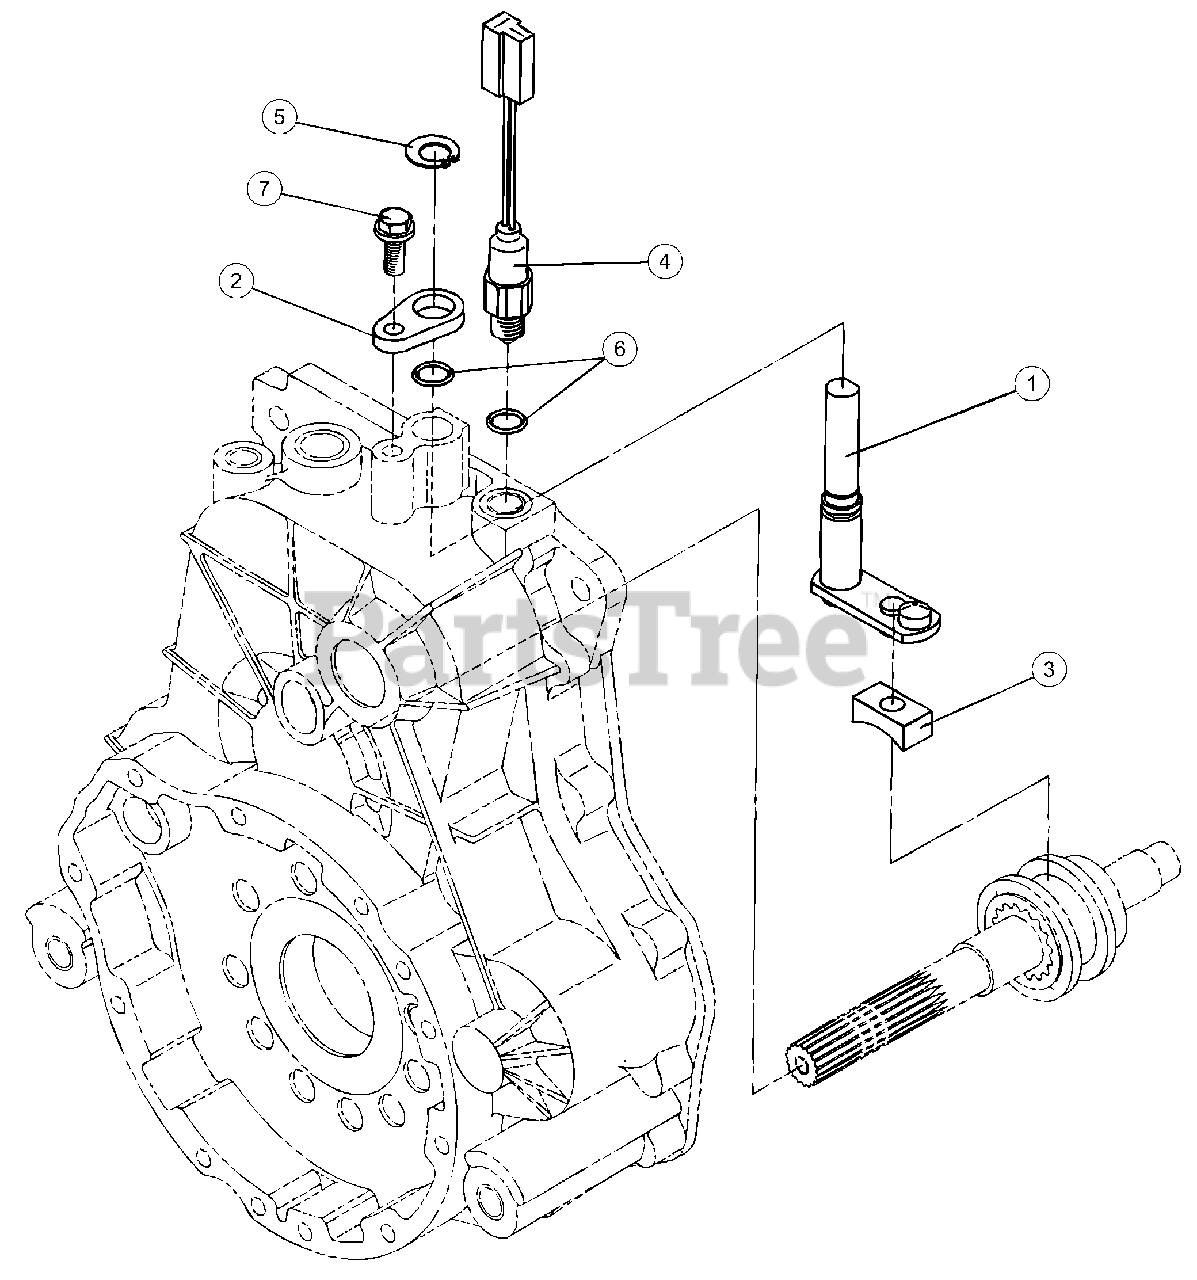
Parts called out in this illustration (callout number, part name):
2	Plate
5	Ring, 14
6	Packing, P 12.5
7	Tapping Screw, 8 x 20
